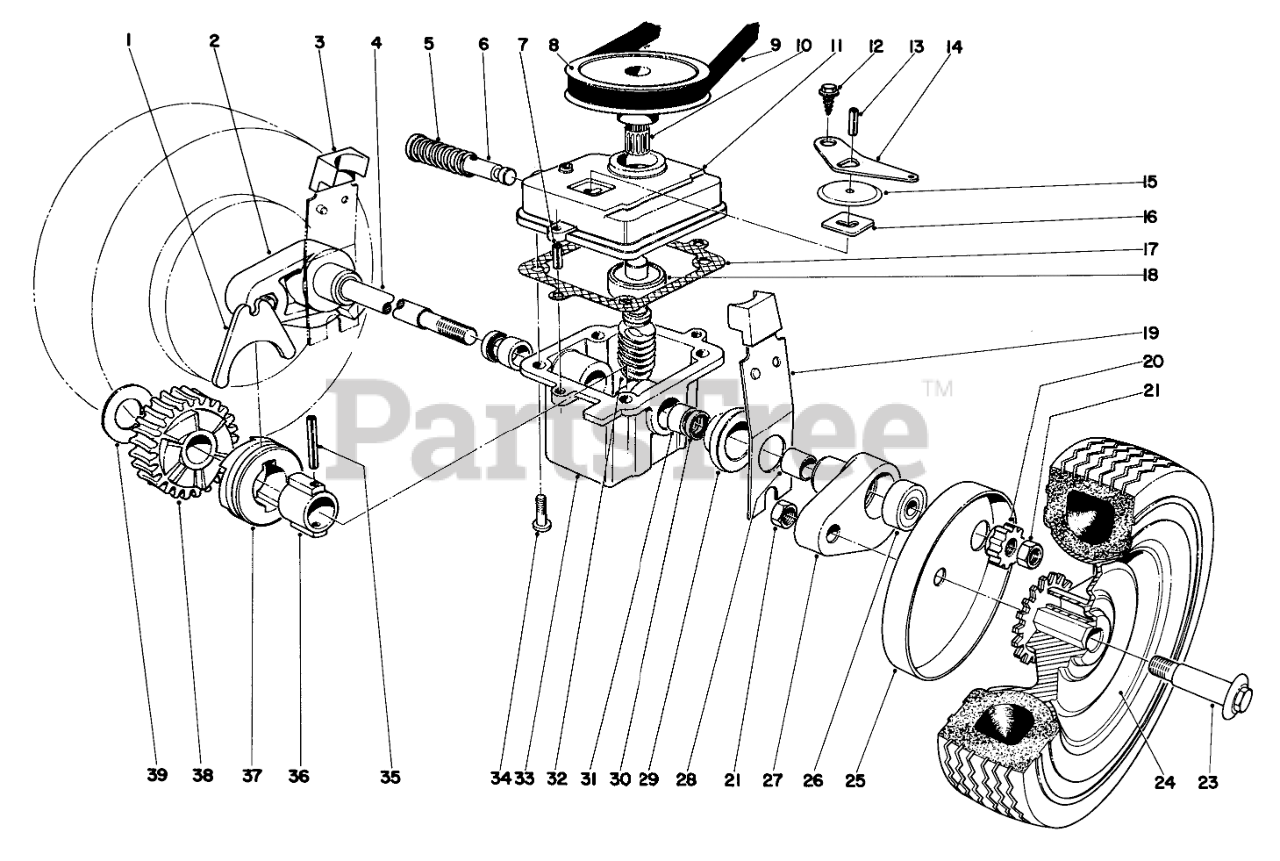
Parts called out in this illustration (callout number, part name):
1	SHIFTER FORK
2	Pivot Arm, R.H. (Incl. Ref. No. 28)
3	Knob
4	DRIVE SHAFT
5	SPRING
6	Shift Rod
7	3/16 X 1/2 ROLL PIN
8	PULLEY
9	V BELT
10	TOLERANCE RING
11	Gear Case Cover (Incl. Ref. No. 18)
12	Screw
13	PIN-ROLL
14	SHIFTER ARM
15	TRANS DUST COVER
16	LATCH PLATE
17	GASKET
18	Bearing
19	LH SPRING ARM ASM
20	PINION GEAR
21	Nut
24	Wheel & Tire (Inc. Ref. No. 22)
25	WHEEL COVER
26	.375 RPP BALL BEARING
27	Pivot Arm, L.H. (Incl. Ref. No. 28)
28	BUSHING
29	End Cap
30	Seal
31	Bushing
32	Worm Shaft
33	Gear Case (Incl. Ref. No. 31)
34	Screw
35	PIN-SPRING
36	SLEEVE
37	Clutch Jaw
38	Worm Gear
39	THRUST WASHER
